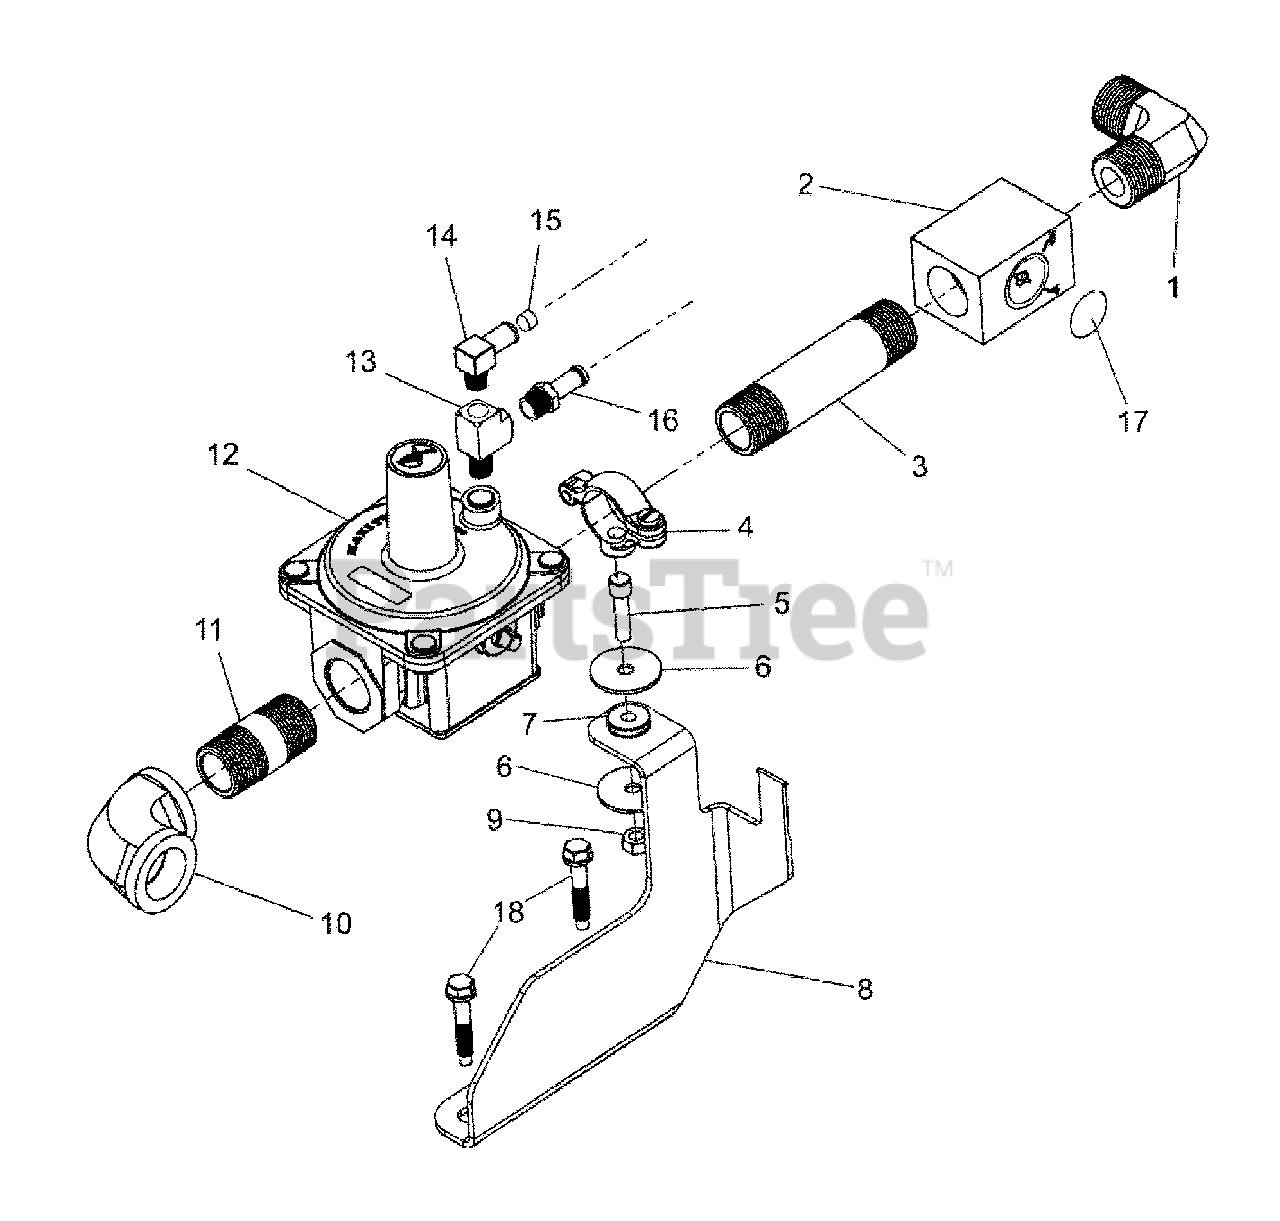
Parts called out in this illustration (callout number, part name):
1	ELBOW
2	FUEL SELECTOR ASSEMBLY
3	PIPE
4	CLAMP
5	STUD
6	WASHER
7	ISOLATOR-RUBBER
8	BRACKET
9	NUT
10	ELBOW
11	PIPE
17	PLUG
18	BOLT
